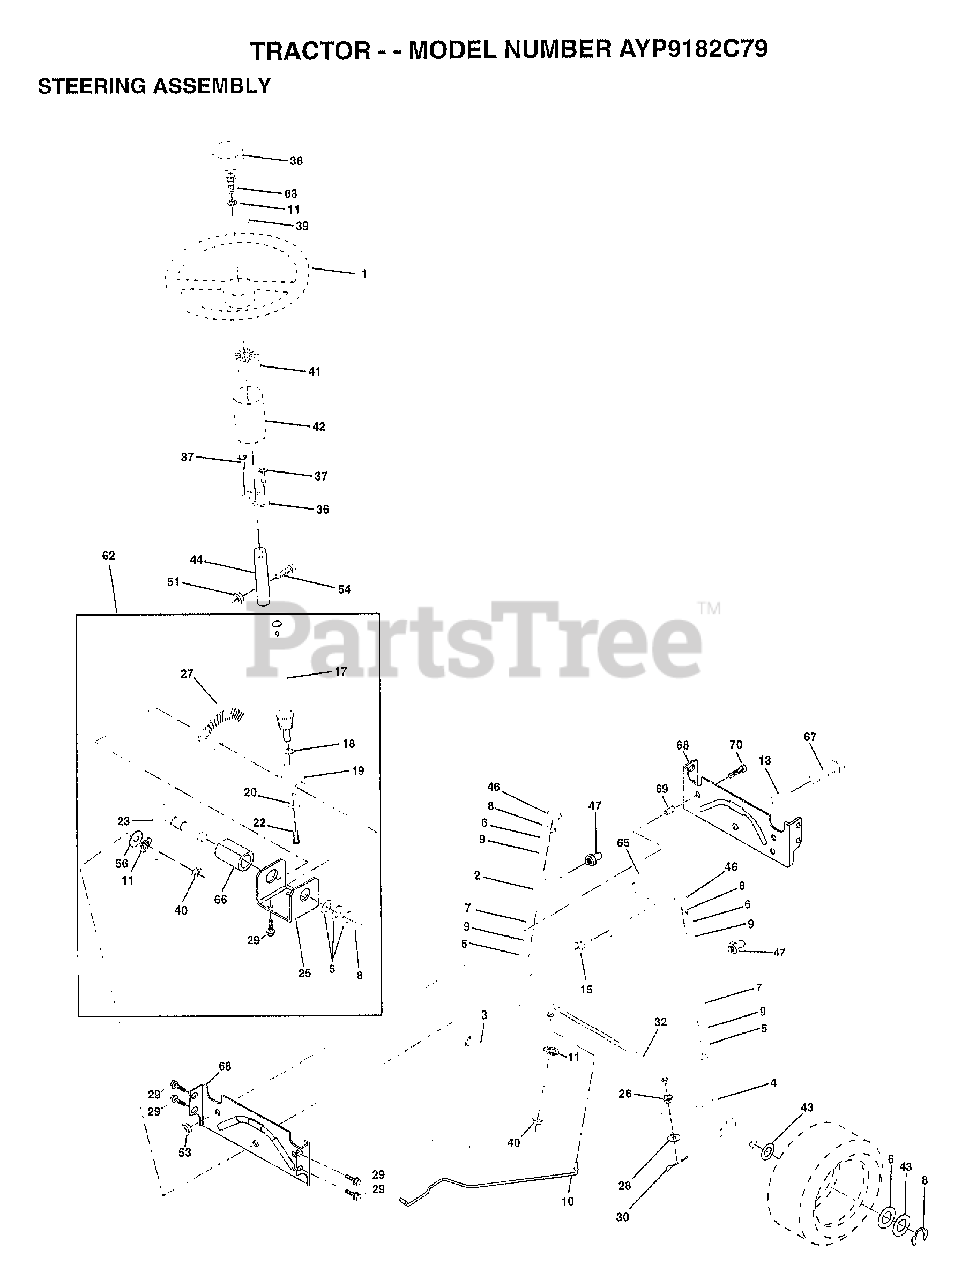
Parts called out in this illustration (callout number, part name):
1	WHEEL STR AYP BLK
2	AXLE ASM
3	SPINDLE.ASM.LH
4	"SPINDLE ASM,RH"
5	WASHER .T
6	WASHER
7	WASHER
8	RING
9	COL. SRTG. BEAR.
10	DRAGLINK-STAMPED
11	LOCKWASHER
13	BEARING AXLE
17	SHAFT ASM STEERIN
18	THRUST WASHER
19	SUPPORT.SHAFT
21	LOCKWASHER
22	SCREW.SCKTHD.CAP
25	BRKT-STEERING
26	BUSHING.DRAGLINK
27	GEAR SECTOR
28	WASHER
29	SCREW
30	COTTER PIN
32	TIE ROD
36	BUSHING.STEERING
37	"SCREW-TT,10-32 FL"
38	CAP STEER AYP
39	WASHER T
40	GRIPCO NUT
41	ADAPTER LT
42	BOOT.STEER.PL
43	WASHER
44	EXT SHAFT STEERIN
46	CAP
47	ZERK M
51	NUT
54	BOLT
62	KIT STEERING ASM
63	BOLT
65	SPACER AXLE
66	"BEARING-ARM,PITMA"
67	BOLT
68	BRACE AXLE
69	"SPACER BRCAE,AXLE"
70	BOLT.HEX.3/8-16X2
